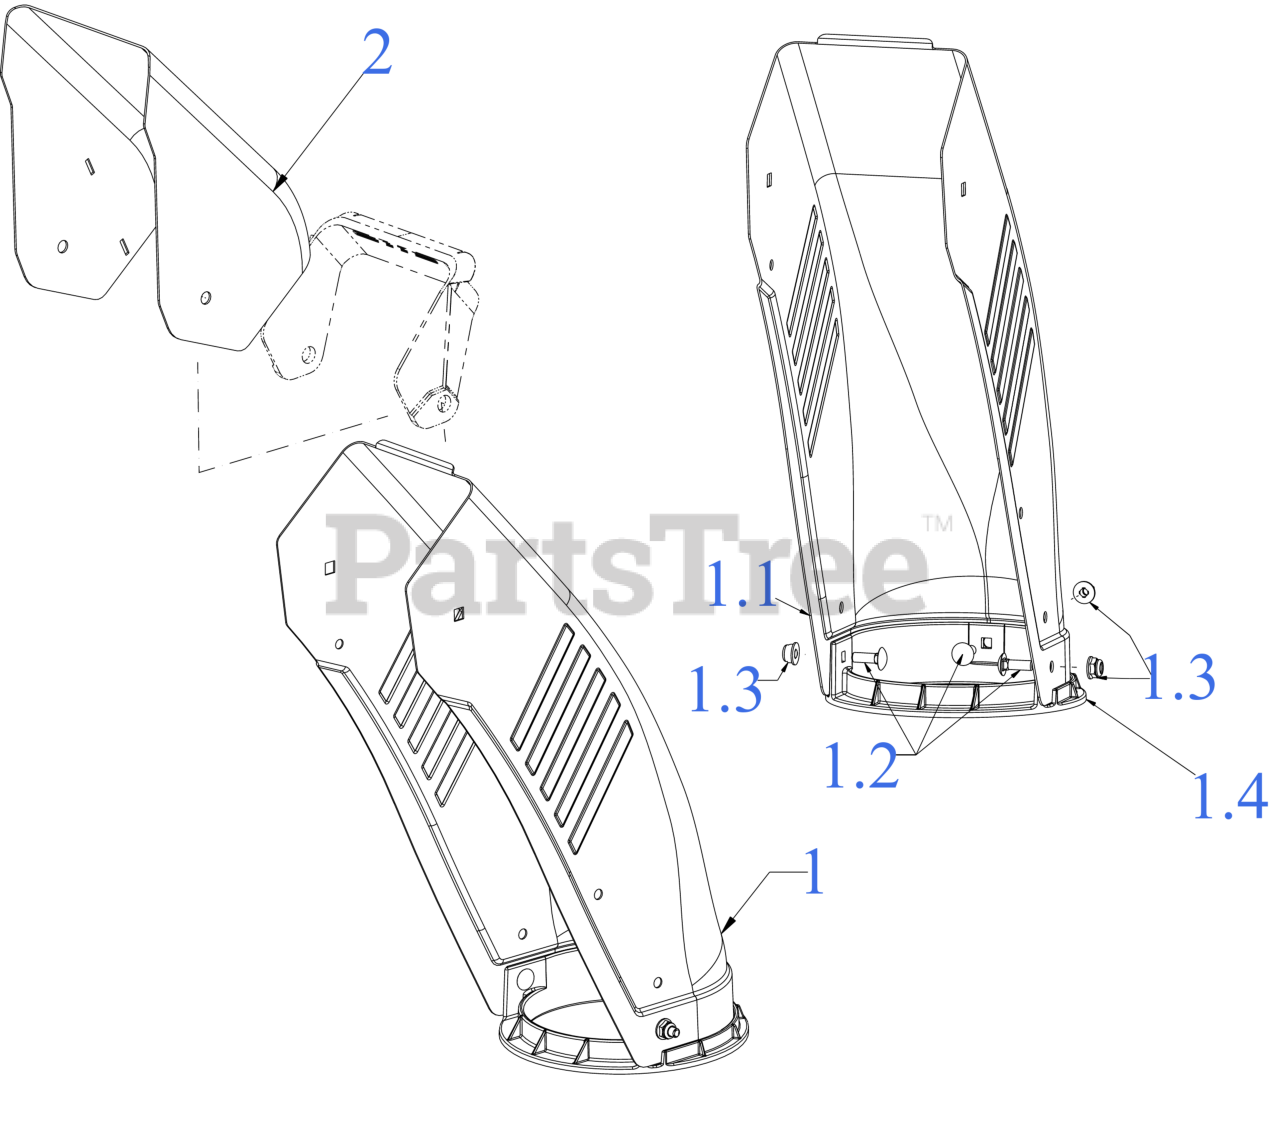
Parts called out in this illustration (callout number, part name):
1	Not Serviceable/ Components Only
1.1	CHUTE 5.5DIA
1.1	STEEL CHUTE
1.2	SCREW 1/4-20 x .75 GR5
1.3	FLANGE LOCK NUT
1.4	CHUTE BASE 5.0 DIA
2	UPPER STEEL CHUTE (REMOTE TILT)
